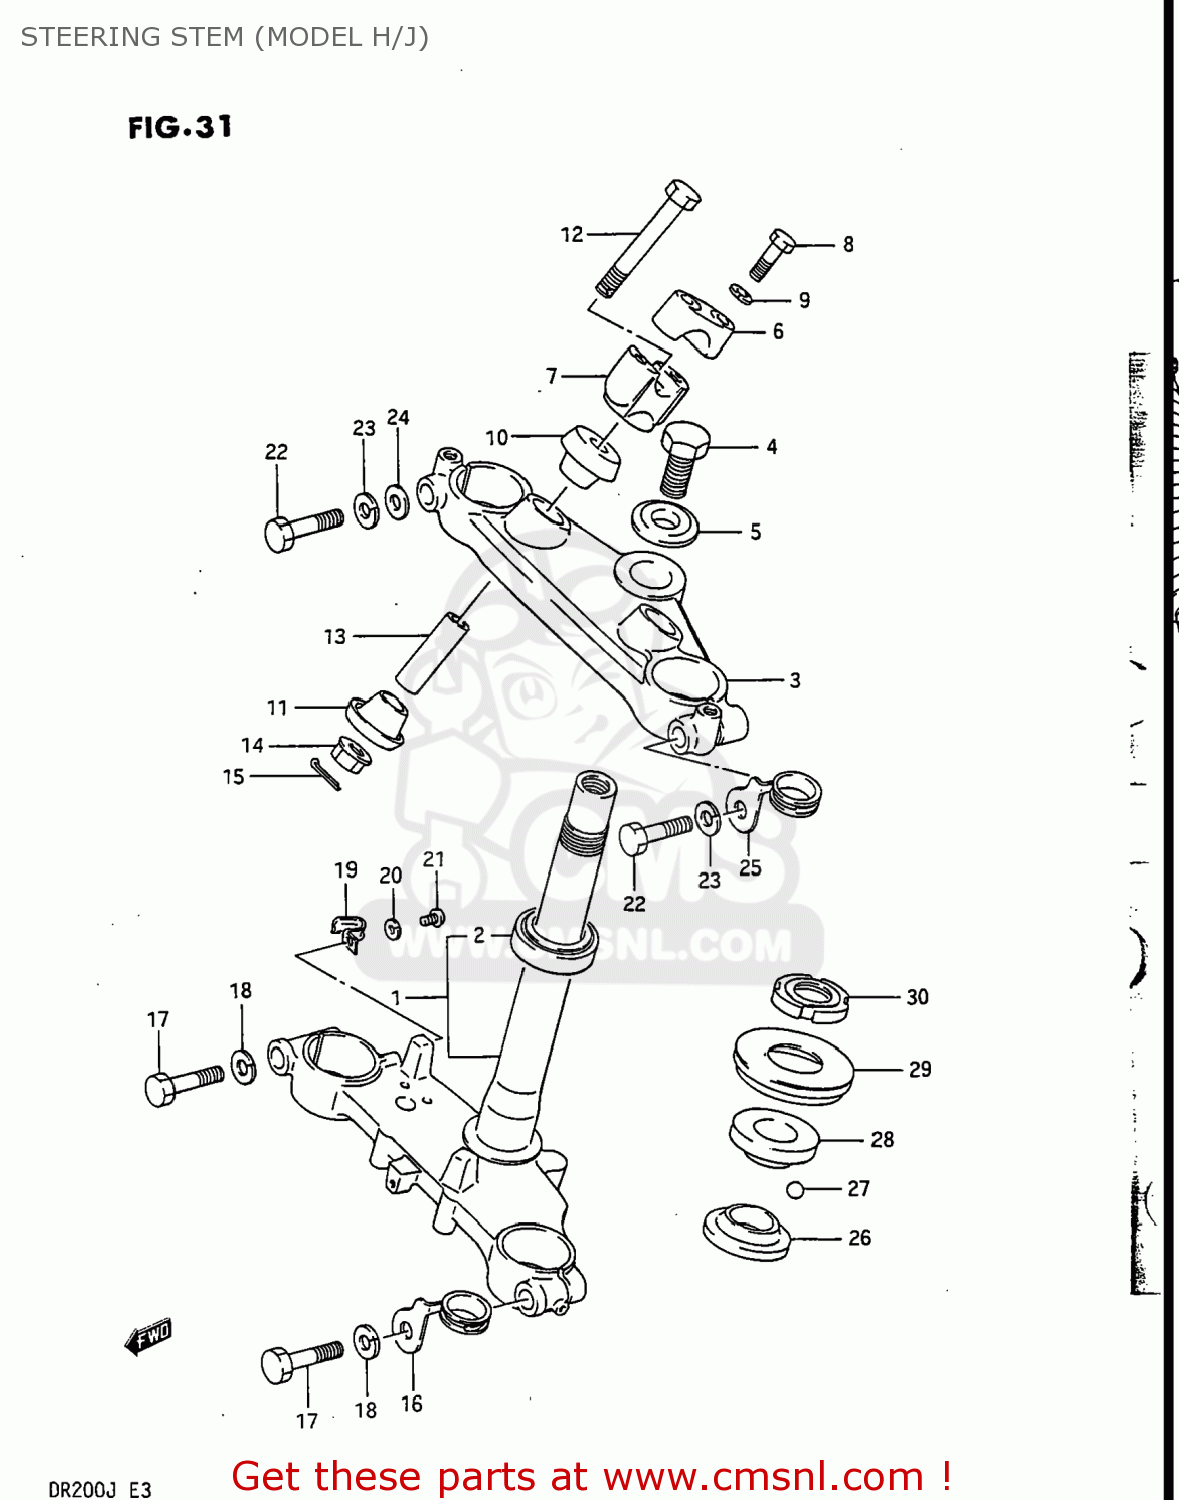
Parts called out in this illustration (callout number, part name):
1	STEM,STEERING
2	BEARING
3	HEAD,STEERING STEM
4	BOLT,STEERING STEM HEAD
5	WASHER
6	HOLDER,HANDLE UPR
7	HOLDER,HANDLEBAR LWR
8	BOLT
9	WASHER,LOCK,8.
10	RUBBER,HANDLE HOLDER
11	RUBBER,LWR
12	BOLT
13	SPACER
14	NUT
15	COTTER PIN
16	CLIP,UPPER
17	BOLT,INNER TUBE FITTING
18	WASHER,LOCK
19	CLIP
20	WASHER,LOCK
21	SCREW
22	BOLT,INNER TUBE FITTING
23	WASHER,LOCK
24	WASHER 10MM
25	CLIP,UPPER
26	RACE,STEERING INNER (SUJ)
27	BALL
28	RACE,STEERING,OUTER,UPPER
29	SEAL,STEERING UPR DUST
30	NUT,STEERING STEM
